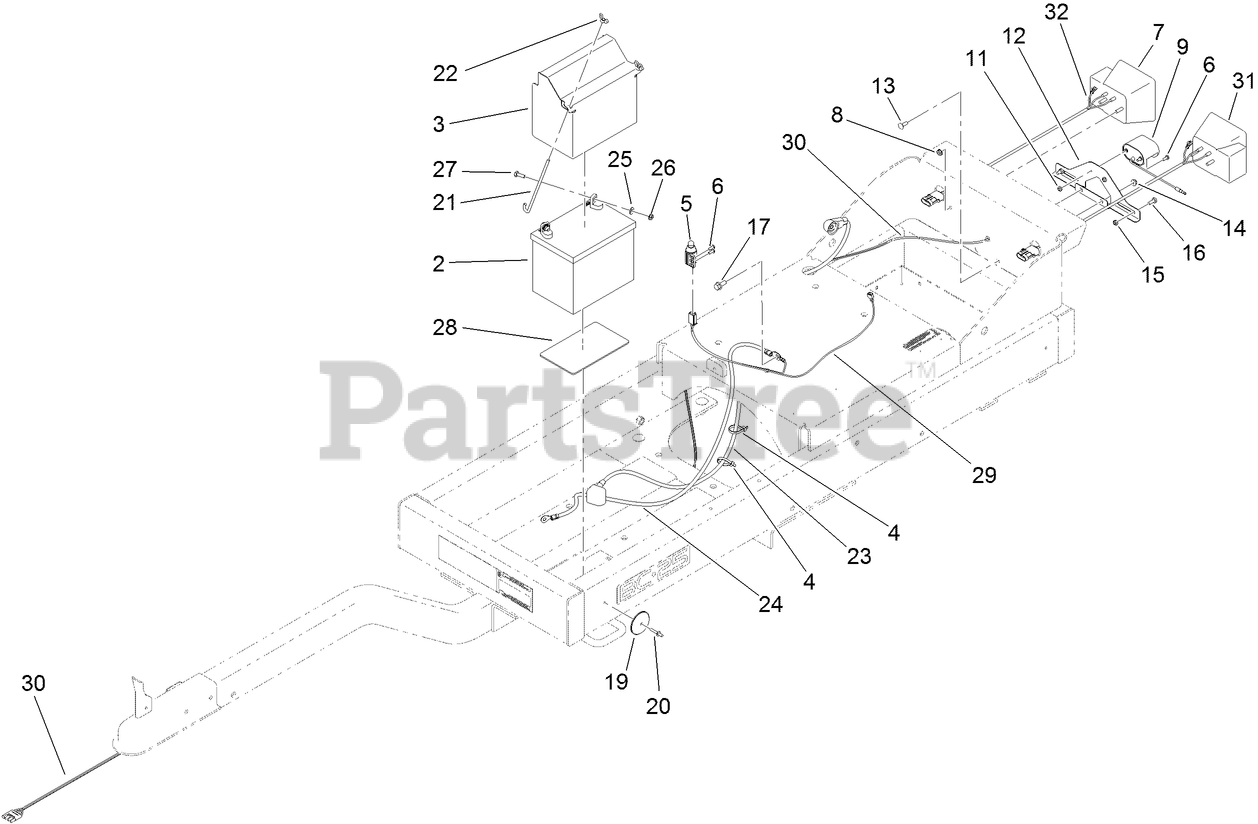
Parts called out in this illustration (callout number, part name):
2	BATTERY-DRY
3	COVER-BATTERY
4	TIE-CABLE
5	SWITCH-PLUNGER, NC (W/COVER)
7	LIGHT-TAIL, RH
8	NUT-KEPS
9	LAMP-LICENSE
11	NUT-LOCK, NI
12	BRACKET-PLATE, LICENSE
13	BOLT-CARR
14	NUT-HF
15	NUT-LOCK
16	SCREW-PPH
17	SCREW-HHF
19	Reflector-Amber
20	RIVET-POP
21	BOLT-HOLDDOWN
22	WINGNUT
23	CABLE-BATTERY, POSITIVE
24	CABLE-BATTERY, NEGATIVE
25	WASHER-FLAT
26	NUT-KEPS
27	SCREW-HH
28	PAD-SKID, ANTI
29	HARNESS-WIRE
30	HARNESS-WIRE, TRAILER (LIGHTS)
31	LIGHT-TAIL, LH
32	HARNESS-WIRE, STUB
